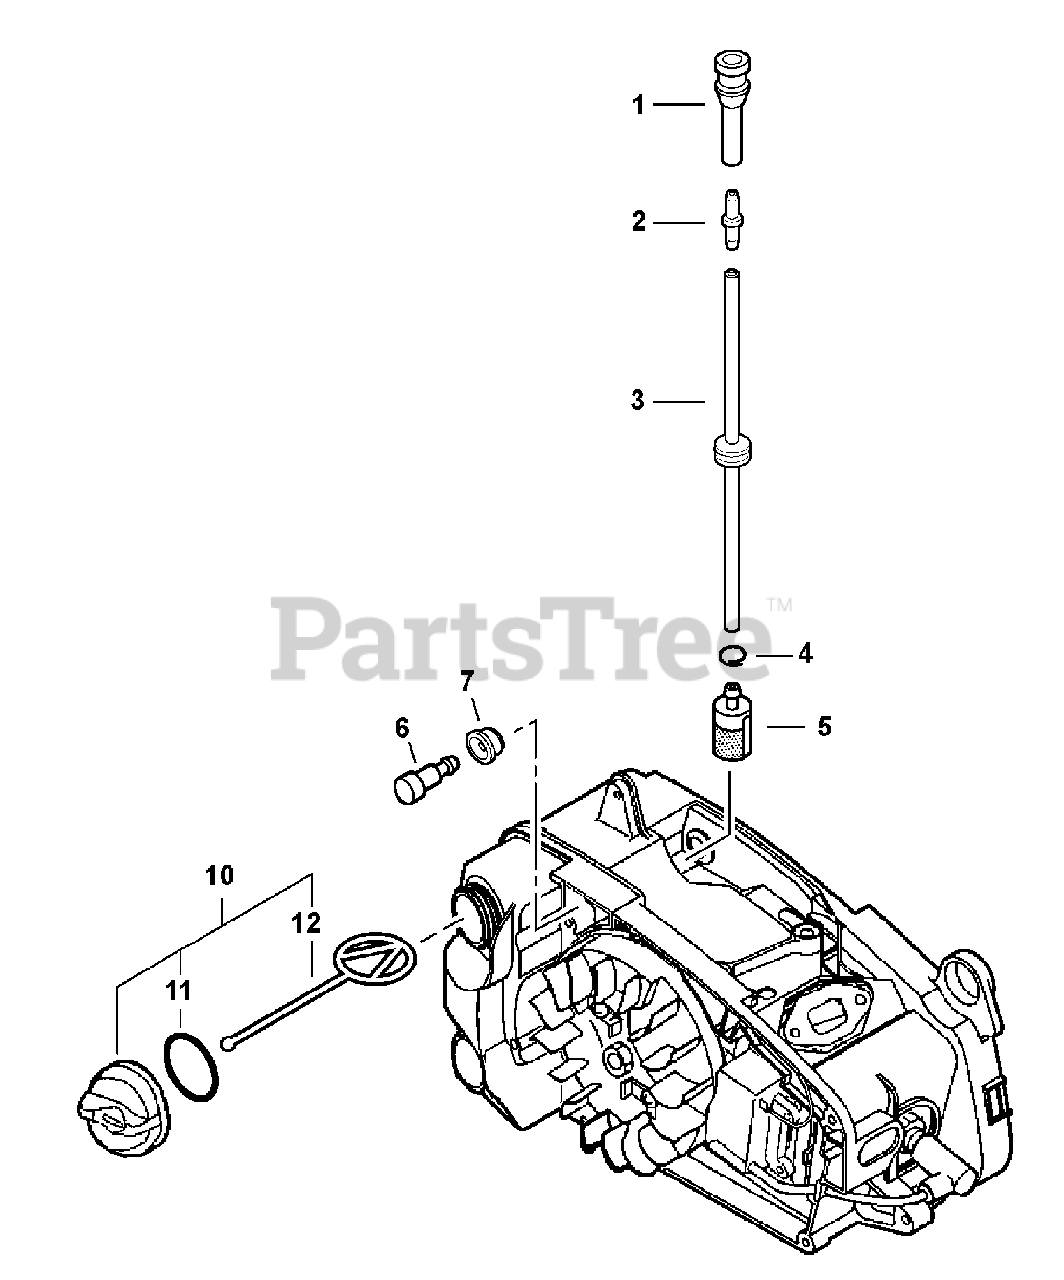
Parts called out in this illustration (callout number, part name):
1	PIPE, FUEL
2	CONNECTOR, PIPE
3	PIPE ASSY, FUEL
4	CLIP 6 MM
5	FILTER, FUEL
6	VENT ASSY
7	GROMMET, FUEL
10	CAP ASSY
11	O-RING 18
12	CONNECTOR, CAP L= 60 MM
